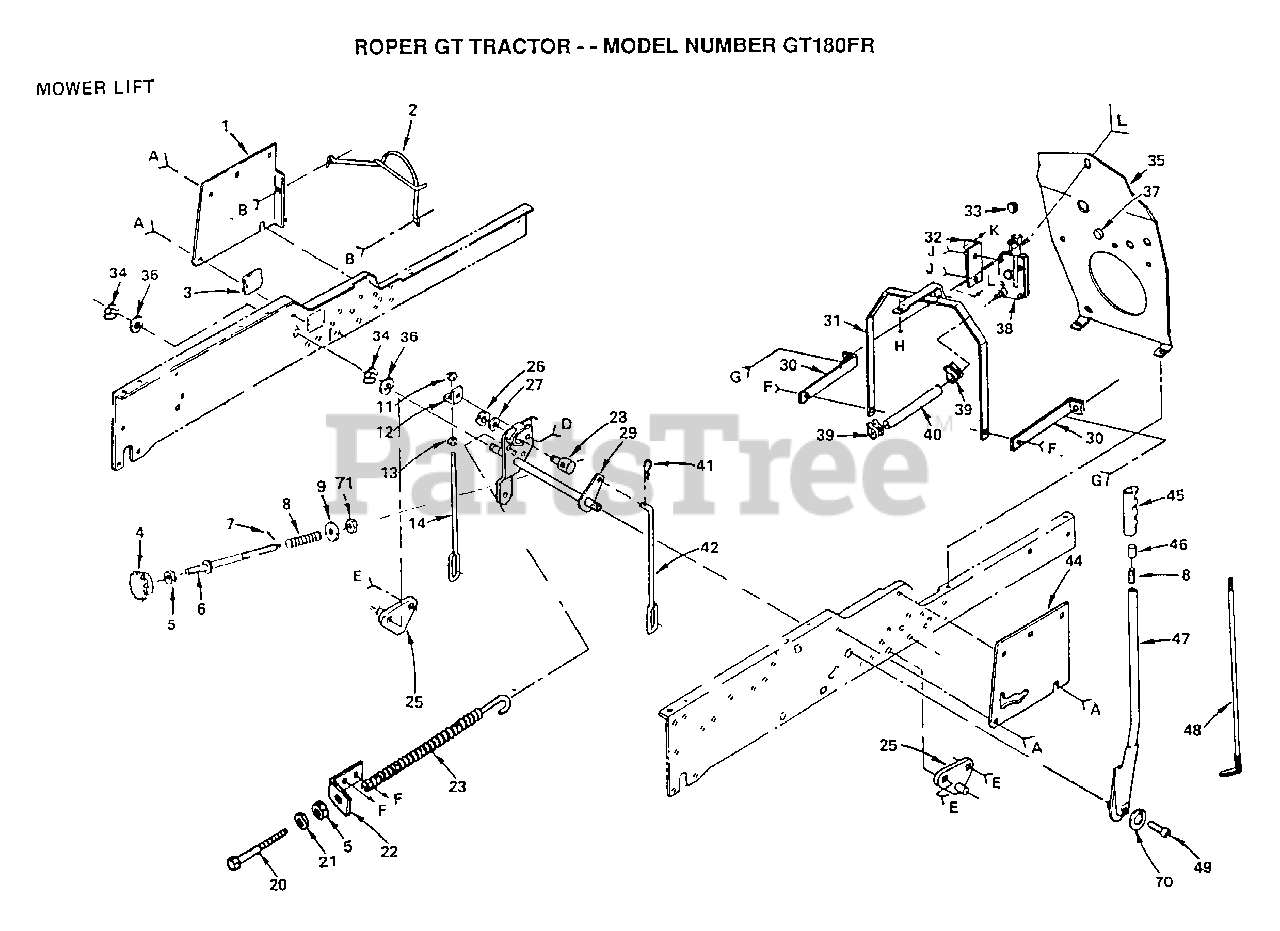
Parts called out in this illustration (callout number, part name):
4	HDLE ADJ LIFT
5	NUT
6	ROD ADJ. T
8	SPRING T
9	WASHER
11	NUT
12	BRACKET T
13	NUT.HEX.3/8-16UNC
14	LINK-LIFT MOW T
20	BOLT-ADJ SPRING T
21	WASHER
25	SUSP BRACKET T
26	KLIP RING
27	WASHER
34	E-RING
35	HEAT SHIELD T
36	WASHER
37	PLUG GT
42	LIFT LINK RH T
45	GRIP
48	LEVER ROD LT
49	"BOLT,HEX"
70	LOCKWASHER
71	NUT T
